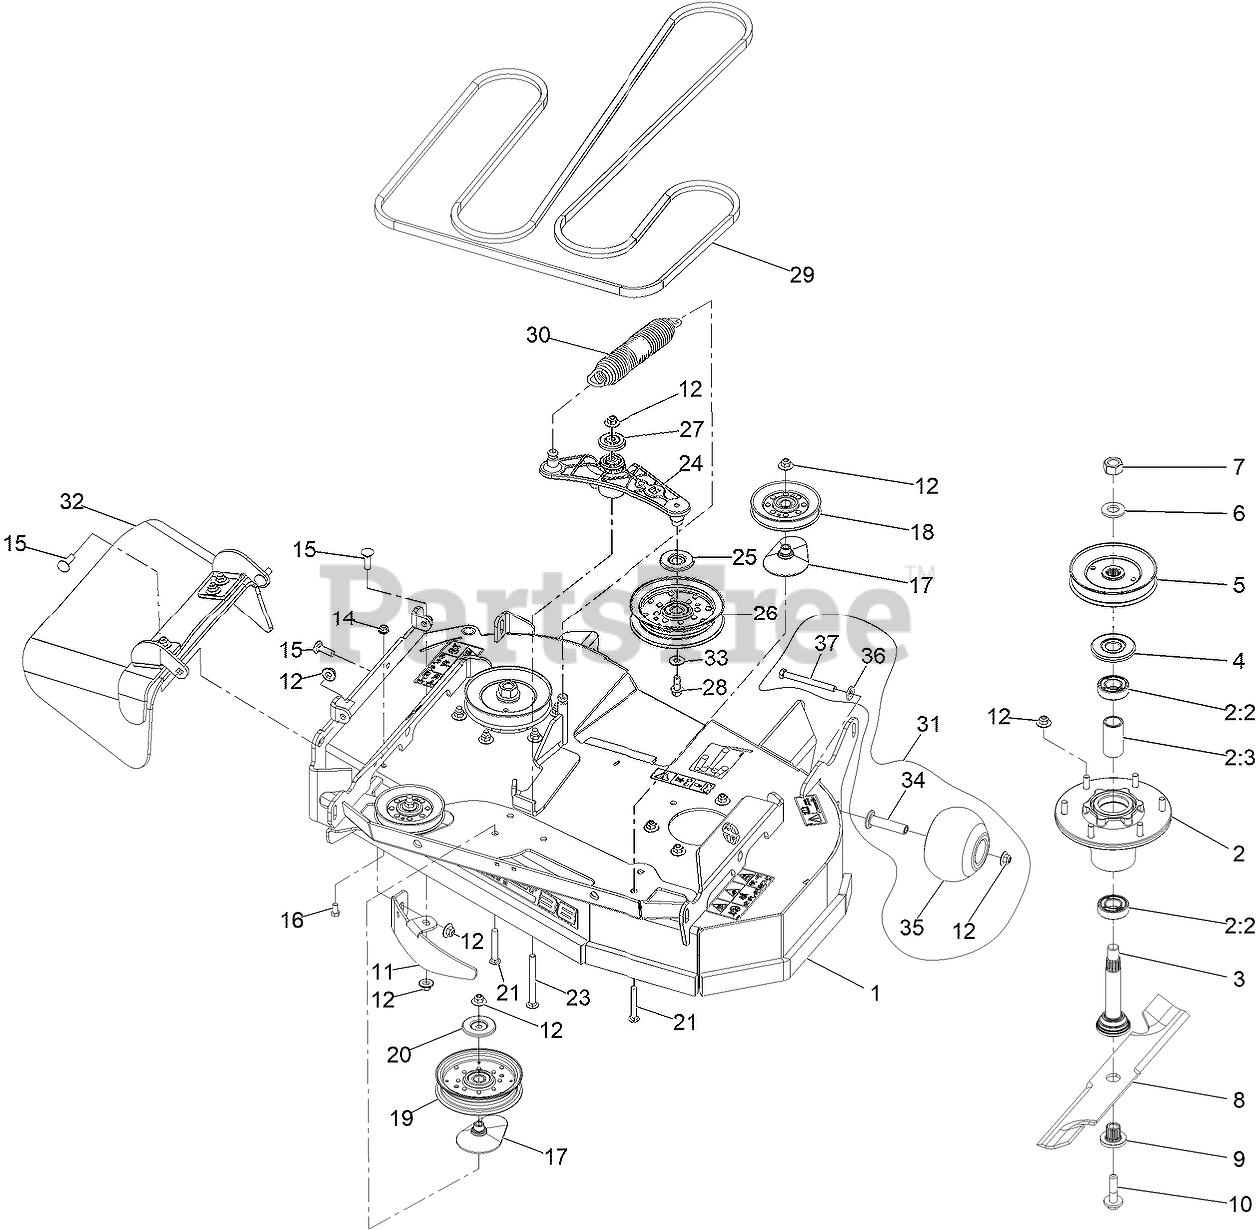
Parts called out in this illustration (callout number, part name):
1	ASM, 36" DECK W/ DECALS
2	ASM-CUTTER HSG WITH BEARINGS
2:2	BEARING-BALL
2:3	SPACER-BEARING
3	ASM-SPINDLE AND SEAL
4	GUARD,BEARING TOP .989
5	SHEAVE-BLADE DRIVE
7	NUT-HEX
9	BUSHING,SPLINED
10	SCREW,SEMS 1/2-20 X 2.19
11	BAFFLE, DOGLEG
12	Nut-Nyloc 3/8-16 Flg
14	NUT-HF, NI
15	BOLT-CARR
16	SCREW-HH
17	SPACER-PULLEY
18	Idler - V 4.13 Eod-A
19	PULLEY-IDLER, FLAT
20	SHIELD-DUST
21	SCREW-CARR
23	SCREW-CARR
24	ASM.-ARM, IDLER
25	SHIELD-GUARD, DUST
26	IDLER-PULLEY, FLAT
27	GUARD-TOP
28	SCREW-HFH
30	SPRING-EXTENSION
31	KIT, ANTI-SCALP ROLLER
32	RUBBER DEFLECTOR ASM
33	WASHER-FLAT
34	AXLE, ROLLER
35	ROLLER-SCALP, ANTI
36	WASHER-BELLEVILLE
37	SCREW-HH 3/8-16 X 3 3/4 GR 8
